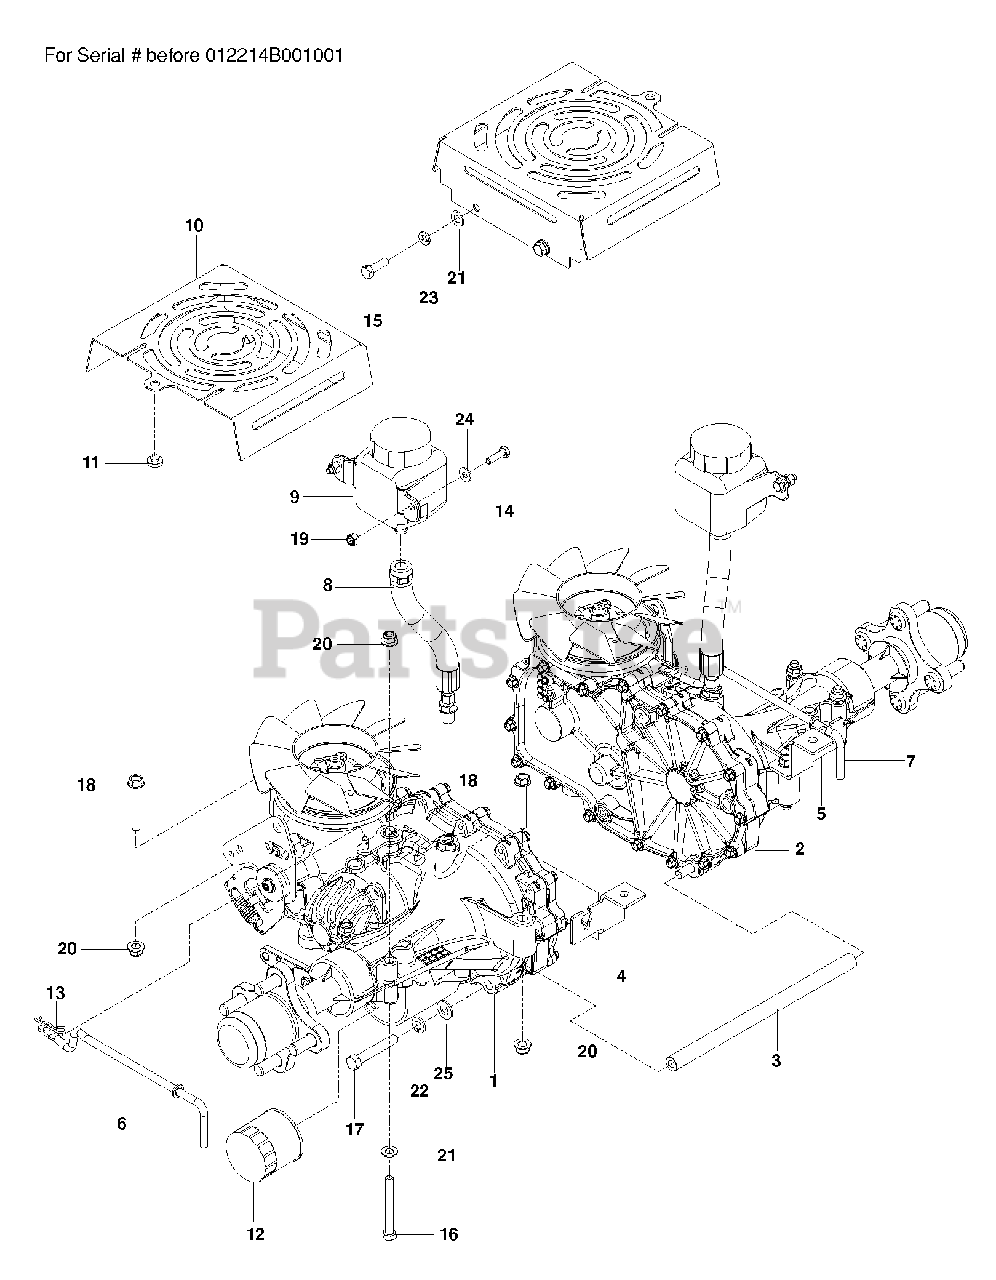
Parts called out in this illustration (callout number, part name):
3	TUBE, SPACER, 3400
6	LINKAGE, LEFT BYPASS
7	LINKAGE, RIGHT BYPASS
8	HOSE ASSY, EXPANSION
9	HG_TANK, EXPANSION, 350ML
10	SHIELD, FAN, BLK
11	GROMMET, BUMPER
12	HG_FILTER, ZT4800
13	HAIRPIN #2
14	HCS 1/4-20X7/8 GR5
15	HCS 5/16C X 1
16	HCS 5/16C X 2-3/4
17	HCS 3/8-16X2-1/4 LOC PATCH GR8
18	HHFS 5/16-18 X 2.25 GD 5
19	NUT 1/4-20 NYLOC
20	5/16-18 NYLOC FLANGE NUT
21	FLAT WASHER 5/16 SAE
22	SLW 3/8 STD
23	WASHER 5/16 LOCK
24	WASHER 1/4 SAE
25	WASHER 3/8 SAE FLAT
